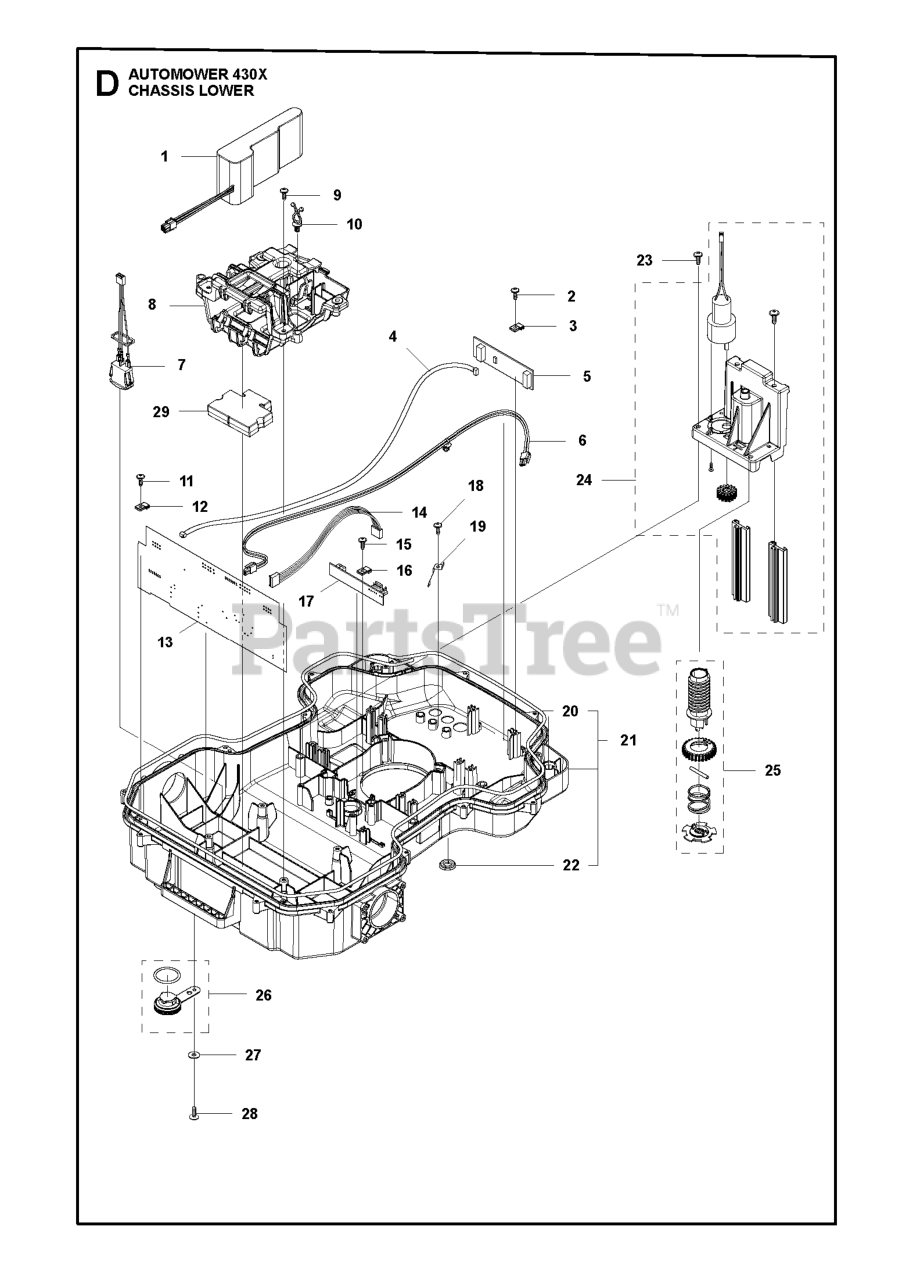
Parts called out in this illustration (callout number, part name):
1	MOWER HOUSING
5	RETAINER-SPRNG RB
6	ARM.SUSPENSION.MOWER.R
7	SCREW
8	BOLT.WASHER.ASM.7/16-2
11	BLADE 38" PREMIUM
13	SHAFT.ASM.MDRL.N/GREASE.38
14	RP.HOUSING.MANDREL.4PT.
19	BOLT.SHOULDER
21	LOCKNUT
23	BRKT.DEFLECTOR.38"2005+
24	CAP-SLEEVE LT
25	SPRING.TORSION.DEFLECT
26	NUT PUSH M
27	SHIELD, DEFLECTOR
29	ROD.HINGE
30	SCREW, WASHER HEAD
31	WASHER.SPACER.MANDREL
32	PULLEY MANDREL 5.0"
33	NUT.FLANGE.LOCK.TOP
34	BOLT.3/8-16X1.50
37	WASHER
38	KEEPER BELT LH MANDREL
40	NUT LOCK FLG 3/8-16 UNC
42	SPRING.TORSION.BRAKE
43	SRPING.TORSION.RETAINE
46	SCREW.1/4-20X5/8
56	SPACER.RETAINER
57	SCREW 3/8-16X1
59	GUARD, BELT
60	BRAKE.ASM.RH.38".TEX.COATED
62	BOLT.3/8-16X1.50
63	BRAKE.ARM.LH.38"TEX.COATED
64	LINKAGE.BRAKE.ASM.ZINC
67	HANDLE.CLUTCH.CABLE.LT
69	BOLT
70	CLUTCH.ASM.MANUAL.LT.PRED
86	PIN ATTACHMENT CABLE
87	SWITCH.INTRLCK.CLUTCH.
115	BOLT.CARR.5/16-18X5/8.SHORT
116	BOLT M
117	WHEEL.GAGE.HALF.SPOKED
118	LOCKNUT
119	WASHER.5/16.FLAT.STE.STD.
122	KEEPER BELT ENGINE LH
123	KEEPER BELT RH
144	KEEPER.BELT.IDLER.PLATED
145	PULLEY.IDLER.FLAT
147	SPRING RETURN
149	SPRING.RETAINER.YELLOW.ZINC
151	BRACKET.CLUTCH CBL.PRED LT
152	CABLE.CLUTCH.MANUAL.W/
186	ARM ACTUATOR
187	LEVER.CONTROL.CL.CABLE.PRED LT
188	STUD.FASTNER.W/ANTI-ROTATE
189	NUT LOCK HEX FLANGE 5/16-18
194	BEARING.CONTROL.LEVER.CLUTCH
195	SCREW, 3/8-16X3/4
197	SPRING.PLUNGER.ACTUATOR
199	BAFFLE.VORTEX.FRONT.38"
209	WASHER 12/32X2X10GA
